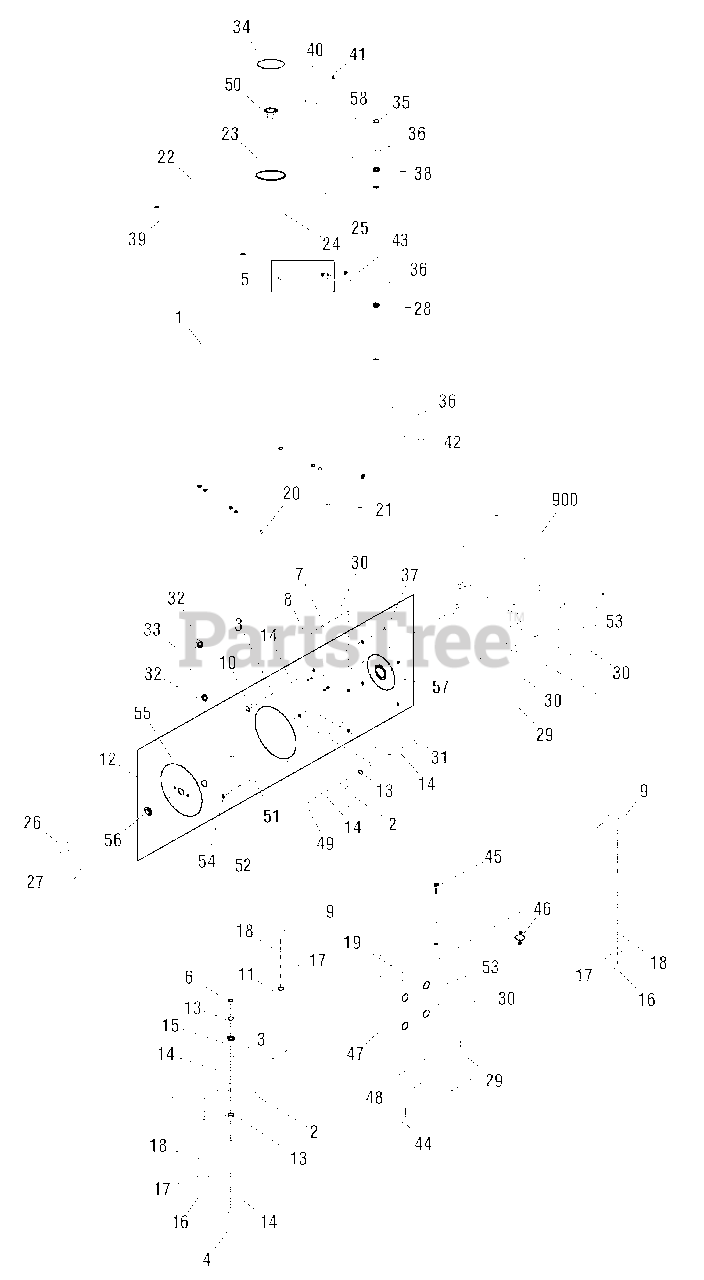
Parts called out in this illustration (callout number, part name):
1	CRADLE (Includes Items 20 & 21)
3	* WASHER, Lock, M8
4	* BOLT, Hex, M8 x 30
5	KIT, Fuel Line
7	* WASHER, Lock, M8
8	* CAPSCREW, Hex Head, 5/16 - 24
9	ABSORBER, Vibration
10	* CAPSCREW, Socket Head, M8 x 30
11	* CAPSCREW, Hex Head
12	ALTERNATOR ASSEMBLY
13	* WASHER, M8
14	* WASHER, Flat, M8 x 16
15	* NUT, Hex, M8
16	* NUT, M10
17	* WASHER, Lock, M10
18	* WASHER, Flat, M10
19	SCREEN, Spark Arrest
21	DECAL, Warning, Exhaust
22	DECAL, Warning CO
23	DECAL , Warning Fuel
24	DECAL, Warning Fuel Fill
25	DECAL, Fuel Instructions
27	WIRE END SEAT, White
29	* CAPSCREW, Hex Head, M8 x 35
30	* WASHER, Flat, M8 x 16
31	* NUT, Nylon M8
32	QUICK CONNECTOR
35	* SCREW, M6 x 30
36	* WASHER, Flat, M6 x 24
37	* NUT, M8
39	ASSY, Tank, Fuel
41	* SCREW, M5 x 10
42	* NUT, Nylon, M6
43	VALVE, Fuel
44	* CAPSCREW, Hex Head, With Lockwasher, M6 1.0 x 12
45	* CAPSCREW, Socket Head, M6 - 1.0 x 20
46	GASKET, Exhaust
48	BRACKET, Muffler
49	* SCREW, M8 x 25
52	WASHER, Capacitor
53	* NUT, Nylon, M8
54	SCREW, Capacitor
58	DECAL, Fuel Shut off
900	** ENGINE
